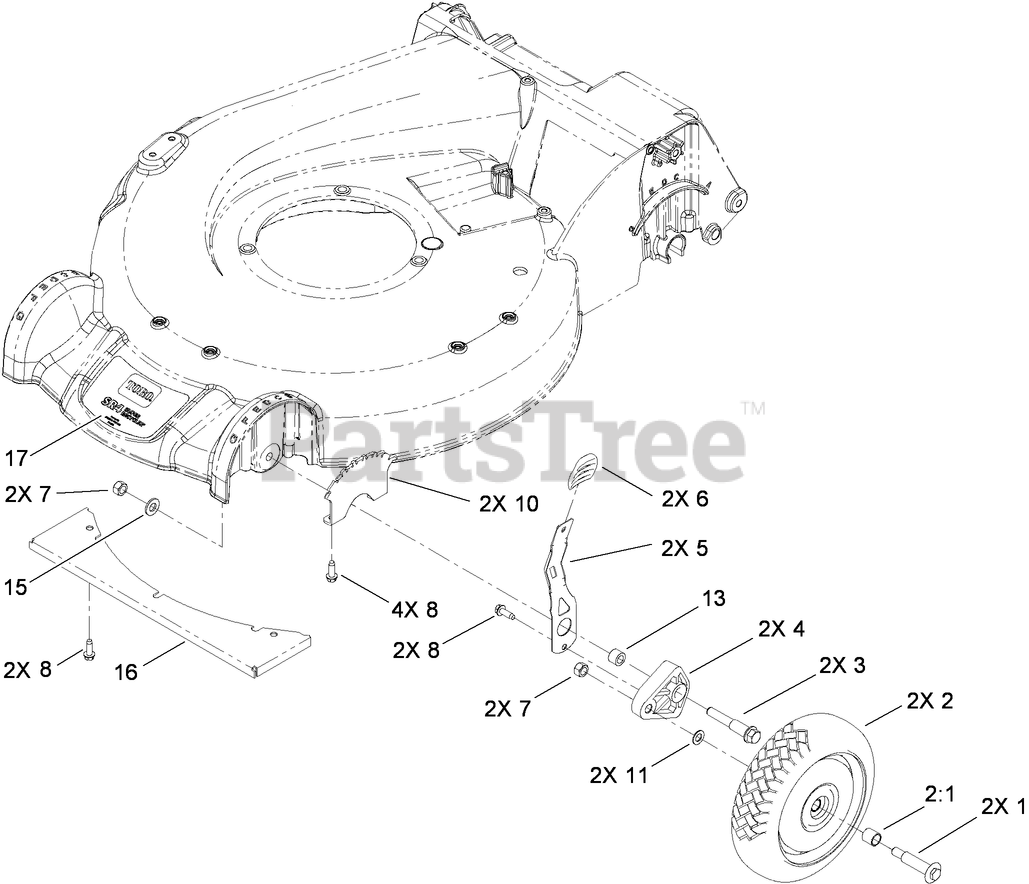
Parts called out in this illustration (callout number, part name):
1	BOLT-SHOULDER
2	WHEEL AND TIRE ASM
2:1	BUSHING
3	SCREW-SHOULDER
4	ARM-PIVOT
5	ARM-SPRING
6	KNOB-LEVER, HOC
7	LOCKNUT
8	SCREW-HWHTF
10	PLATE-HOC
11	WASHER
13	SPACER-WHEEL
15	WASHER-FLAT
16	PLATE-COVER, FRONT
17	DECAL-HOUSING
